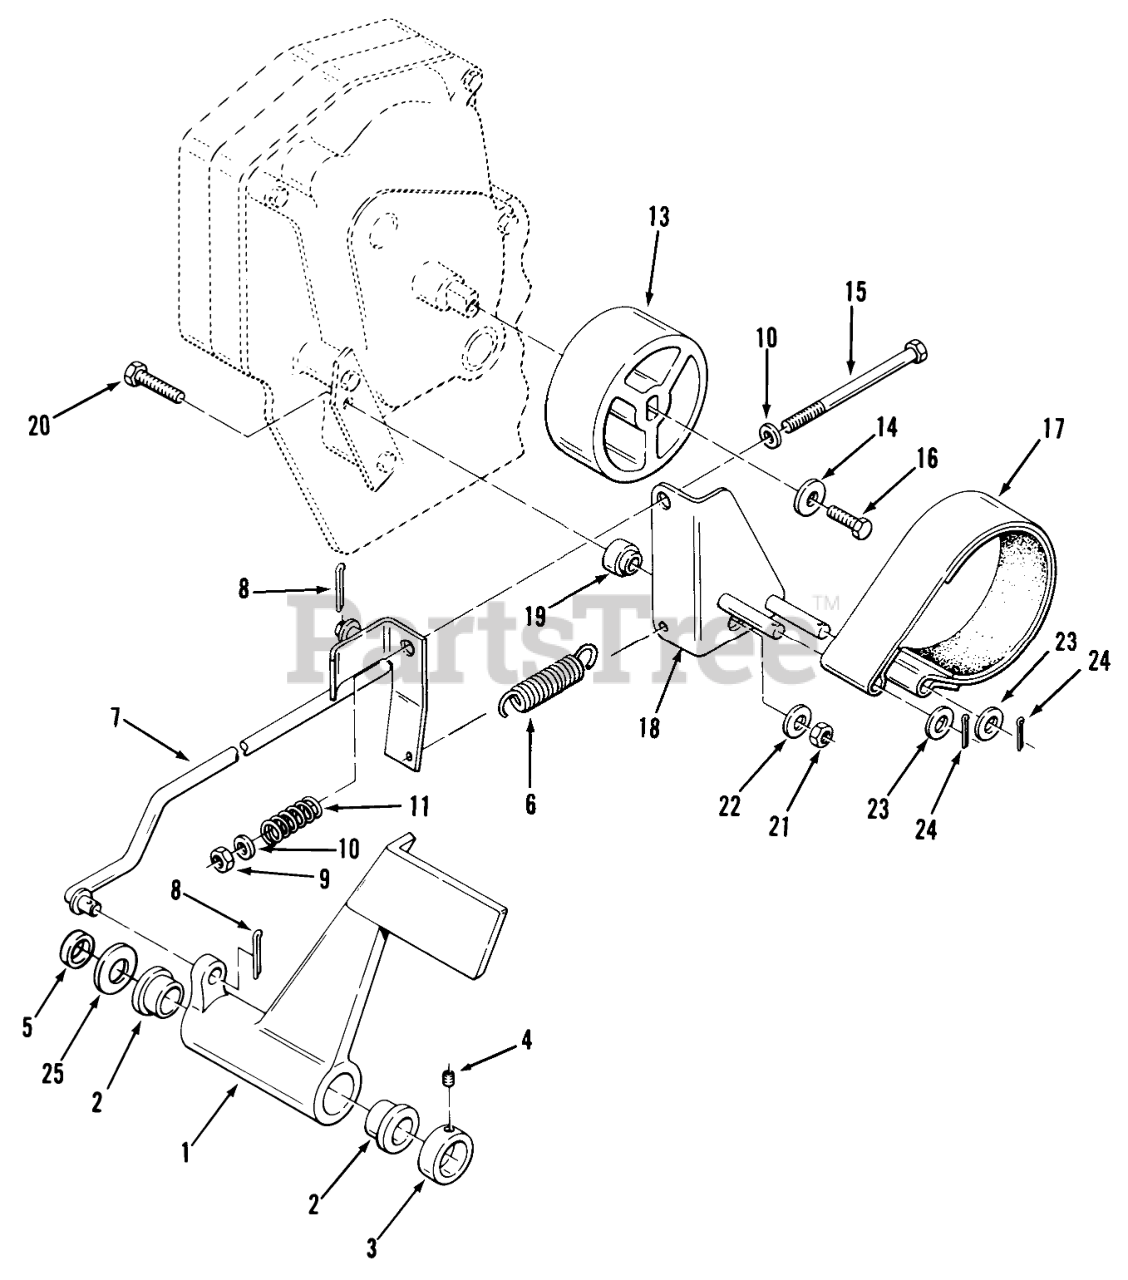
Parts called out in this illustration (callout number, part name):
1	PEDAL R
2	BUSHING
3	Collar
4	SCREW-SET
5	SPACER FRONT PULL R
5	Spacer
6	SPRING
7	BRAKE ROD ASSY R
7	ASY BRAK RD WAR
9	NUT
10	Washer
11	SPRING-COMPRESSION
13	DRUM-BRAKE
14	WASHER
15	BOLT
16	BOLT
17	ASSY-BRAKE BAND
18	Brake Pivot Arm
19	BUSHING-BRAKE PIVOT
20	BOLT
21	Nut
22	Washer
23	Washer
24	Cotter Pin
25	WASHER
